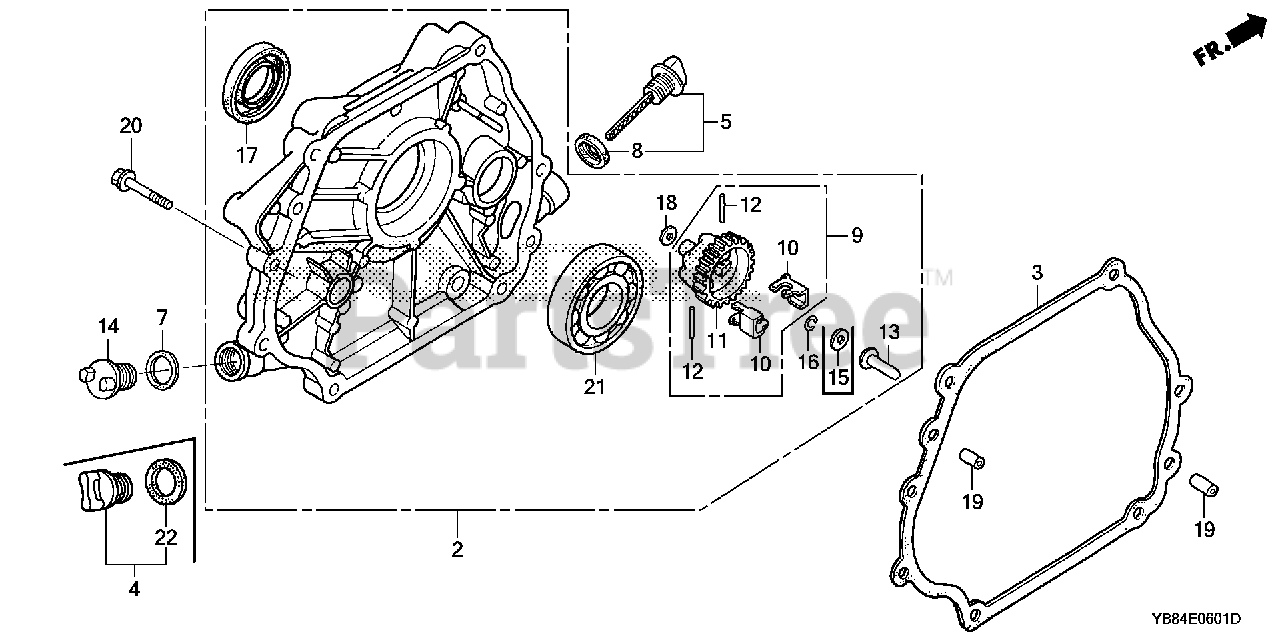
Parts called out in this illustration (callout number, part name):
2	COVER ASSY., CRANKCASE
3	GASKET, CASE COVER
5	CAP ASSY., OIL FILLER
7	GASKET, OIL FILLER CAP
8	GASKET, OIL FILLER CAP
9	GOVERNOR ASSY.
10	WEIGHT, GOVERNOR
11	HOLDER, GOVERNOR WEIGHT
12	PIN, GOVERNOR WEIGHT
13	SLIDER, GOVERNOR
14	CAP, OIL FILLER
14	CAP, OIL HOLE
15	WASHER (6X16)
16	CLIP, GOVERNOR HOLDER
17	OIL SEAL (30X45X8)
18	WASHER, PLAIN (6MM)
19	PIN, DOWEL (8X12)
19	PIN A, DOWEL (8X12)
19	PIN, DOWEL (8X14)
20	BOLT, FLANGE (8X35)
21	BEARING, RADIAL BALL (6206)
